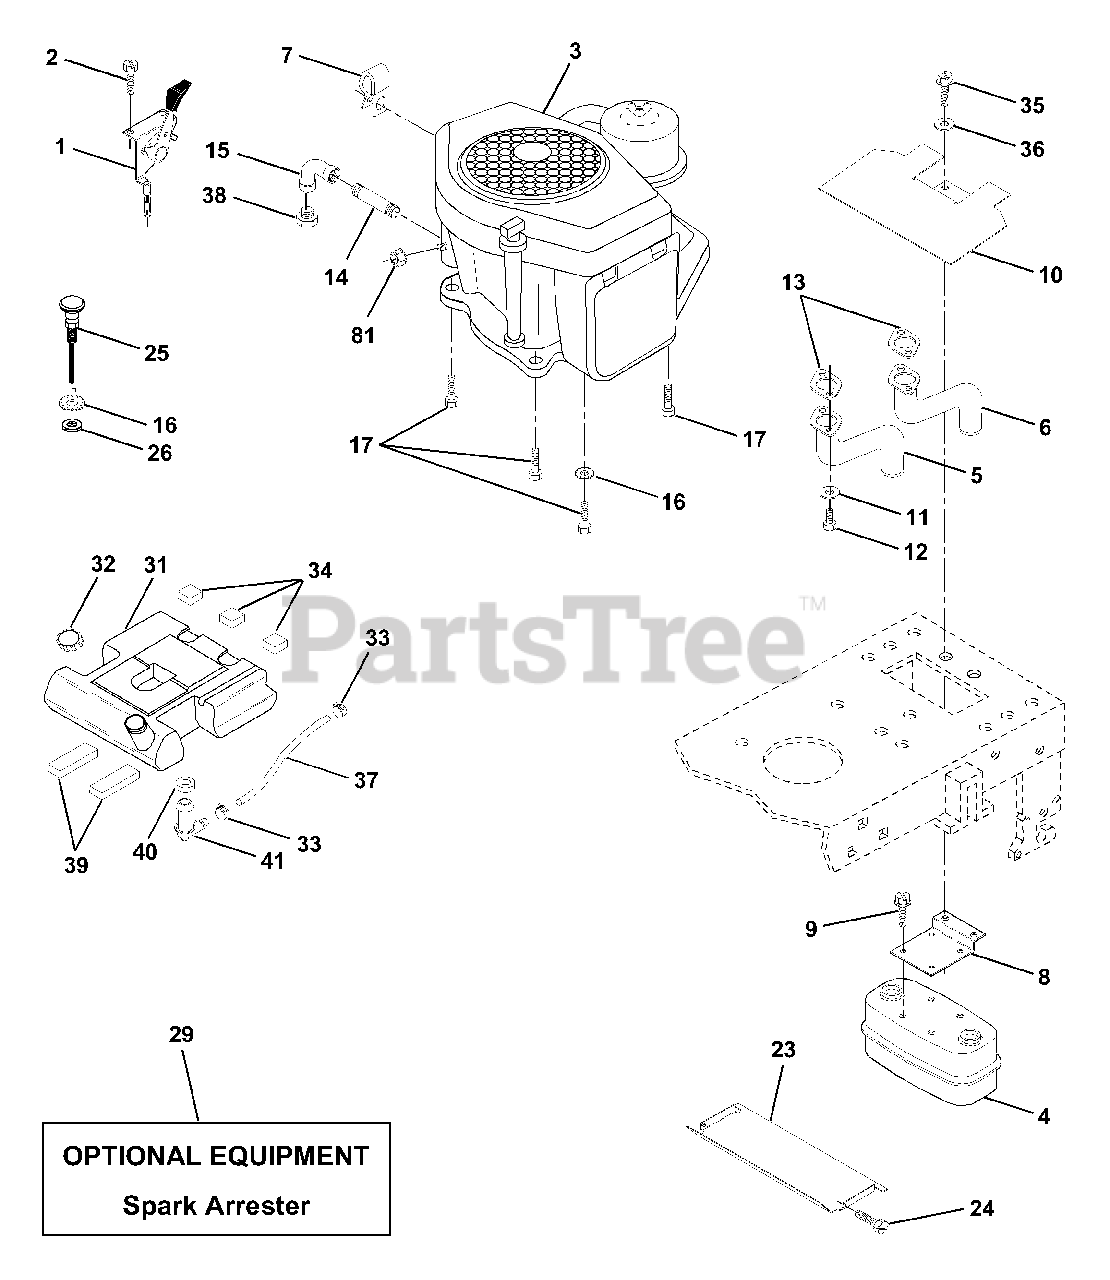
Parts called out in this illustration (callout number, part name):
1	Control RH Blk Flg 37 88
2	Screw Hex Thd Cut 1/4-20x5/8 T
4	Muffler LT B&S
5	Tube Manifold LH
6	Tube Manifold RH
7	Clip Line Fuel 13/32 Mtg. Hole
8	Bracket Muffler Mounting
9	Screw Hex Wsh Thd Cut 1/4-20
10	Shield Heat LT
11	Washer Lock Hvy Hlcl 1/4
12	Bolt, Fin Hex 1/4-20 x 3/4
13	Muffler Gasket
14	Nipple Pipe 3/8 Npt X 4-1/2"
15	Elbow Std 90 Degree 3/8-18 Npt
16	Washer Lock Ext Tooth 3/8
17	Screw Thdrol 3/8-16 x 1-1/2
23	Shield Heat Browning LT/YT
24	Screw Tap Hex #10-24unc X 1/2
25	Choke Control
26	Nut, Fin Hex 3/8-24 Unf
29	Kit Spark Arrestor (Flat Scrn)
31	Tank Fuel 3 50 Rear
32	Cap Asm Fuel W/sym Vented
33	Clamp Hose Blk
34	Pad, Spacer
35	Screw Thdrol 5/16-18 x 3/4
36	Washer 13/32 x 1-1/4 x 12 Ga.
37	Line Fuel 54"
38	Plug Oil Drain
39	Pad, Idler
40	Bushing
41	Stem Tank Fuel
81	Nut Keps Hex 1/4-20 Unc
